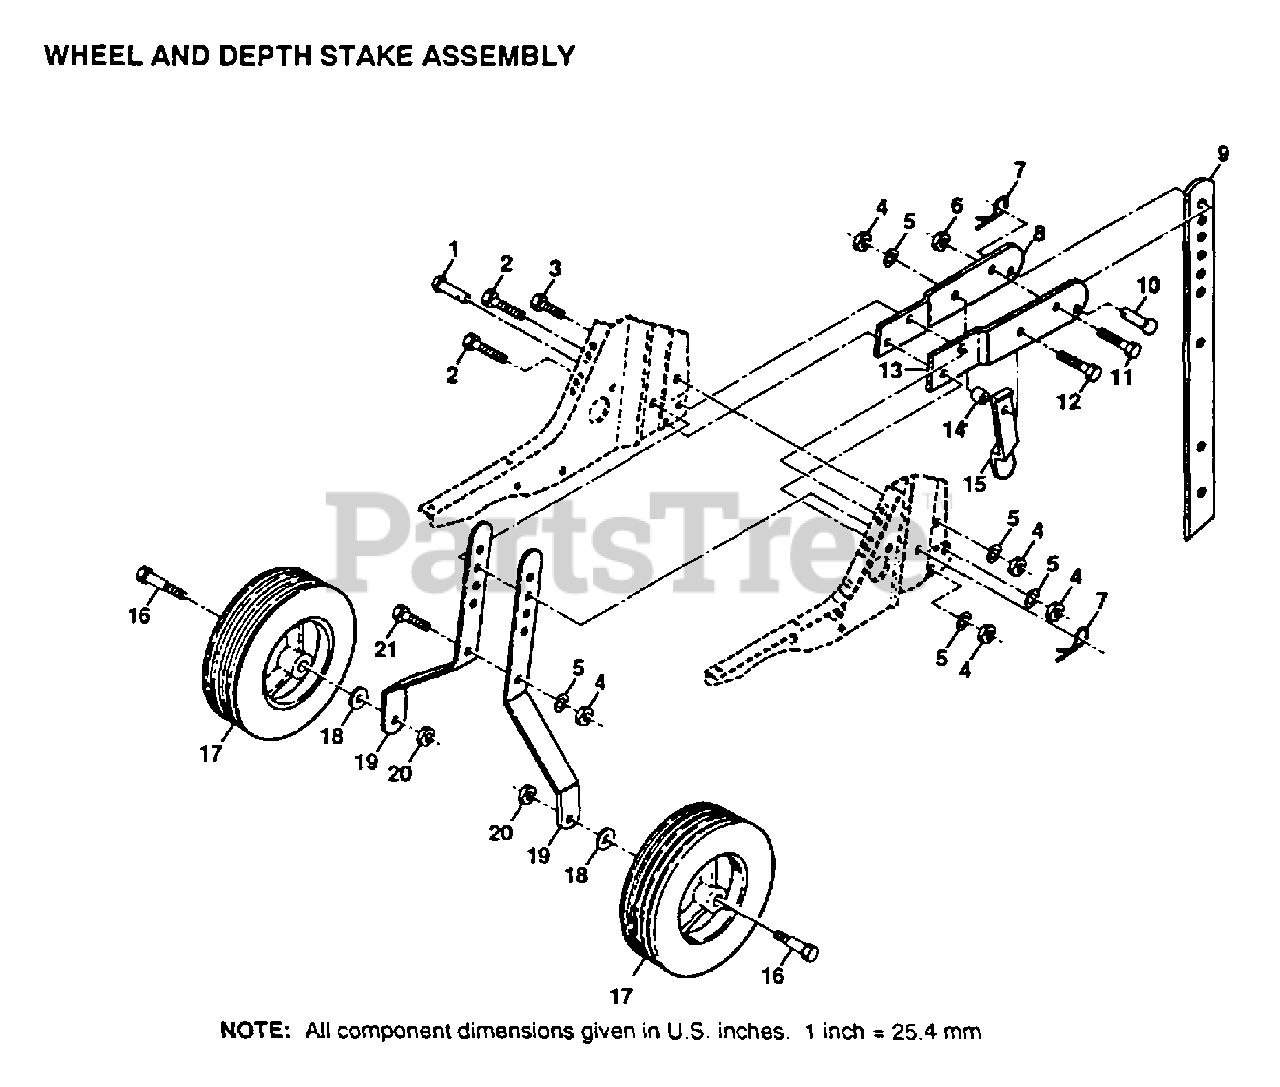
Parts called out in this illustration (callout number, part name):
1	DRILLED RIVET RT
3	BOLT
4	NUT.HEX.5/16-18
5	LOCKWASHER
6	GRIPCO NUT
7	SPRING.RETAINER
11	BOLT.3/8-24X1-1/2
12	BOLT.HEX.5/16-1.5
14	WASHER
15	STAKE SPRING TI
16	BOLT SHOULDER
18	WASHER
